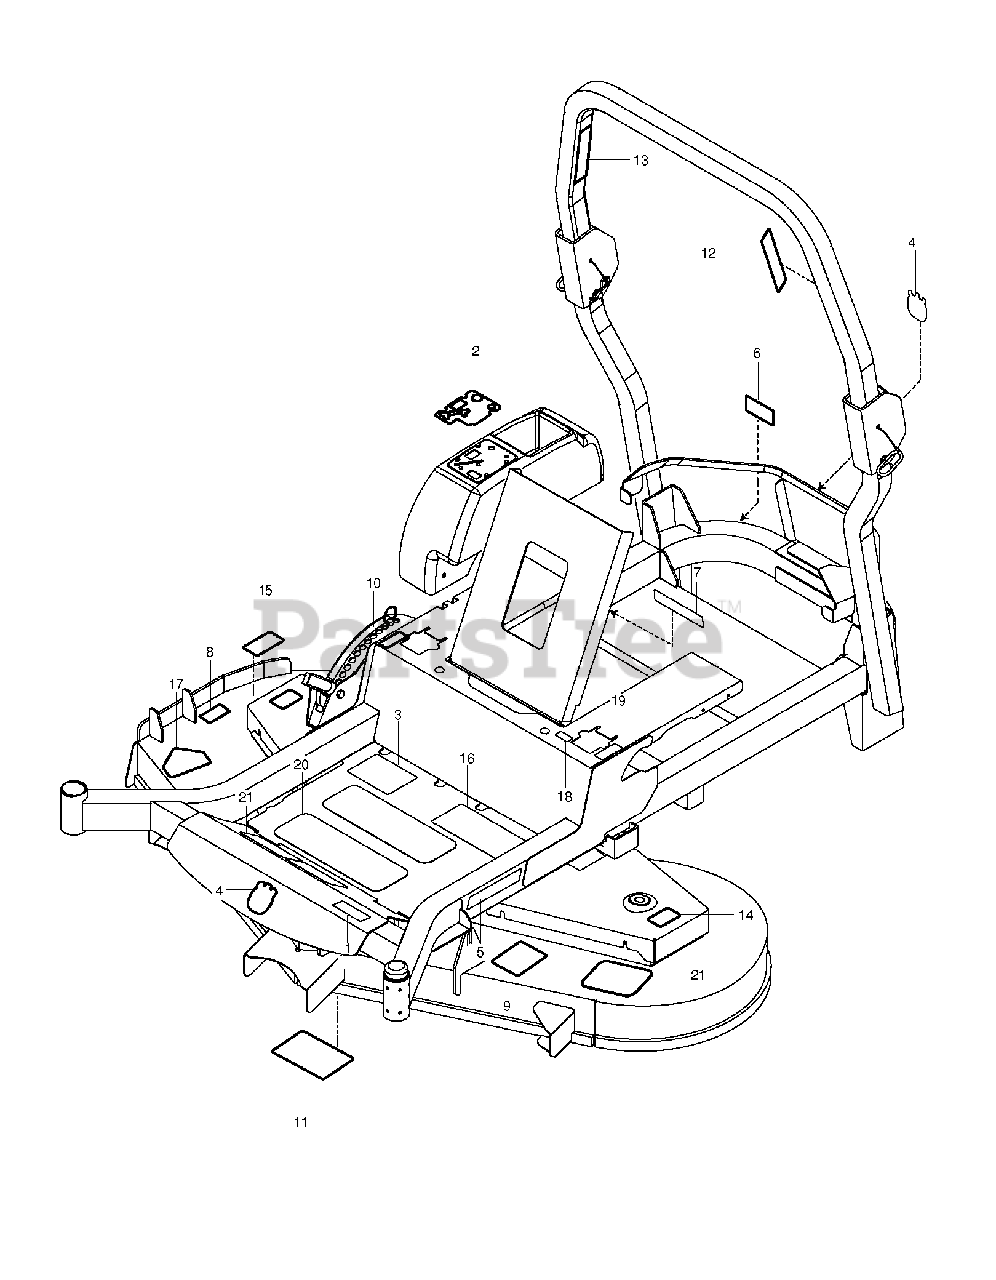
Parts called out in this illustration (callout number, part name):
1	DECAL.ZTR.96704550100.MZT61EFI
2	DECAL, CONSOLE,EFI HUSQ
3	DECAL.ZTR.STRTNGINST.REMTCHK
4	DECAL.AUGER.HUSQ.CROWN.SNOW
5	RP.DECAL.BADGE.170MM.TEXTLOGO
6	DECAL, BELT DRIVE
7	EURO DECAL-BATTERY WARNIN6
8	DECAL, EURO SEVERING
9	DECAL, BELT ROUTING
10	DECAL, HEIGHT ADJUST
11	DECAL, SERVICE
12	DECAL, ROPS, WARNING
13	DECAL ROPS
14	DECAL.DECK.6MIL.EURO.NOSTEP
15	DECAL.DECK.6MIL./DEF.SHLD.WARN
16	DECAL.ZTR.WARNING.SMARTIGNITIN
17	DECAL, DECK DEFLECTOR, WARNING
18	DECAL, F.S.T.
19	DECAL.ZTR.MOTCONTRL.SYMBOL.HUS
20	ANTI-SKID PAD
